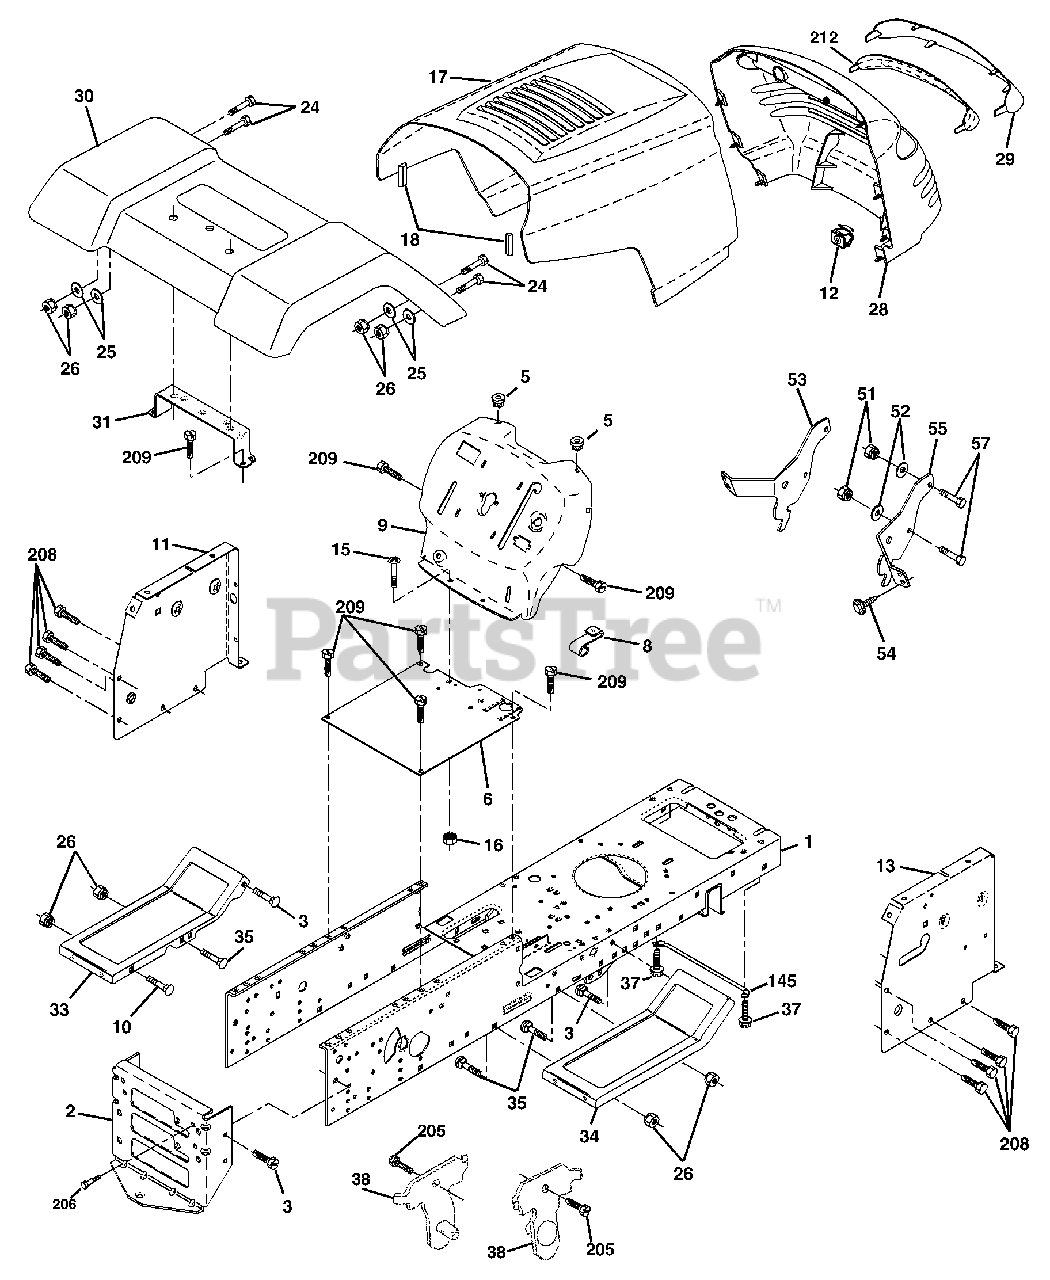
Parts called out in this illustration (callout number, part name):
1	Chassis
2	Drawbar
3	Screw 3/8-16 x 3/4
5	Bumper Hood/Dash
6	Saddle Slkscr Flat Lt 6 Sp
8	Clip Retainer Slide-On
9	Dash
10	Bolt Rd Hd Sqnk. 3/8-16 Unc x 1
11	Panel Asm. Dash Lh
12	Clip Tinnerman Grile P/L
13	Panel Dash Rh
15	Screw Mach Trhd 5/16-18 Unc x 3/4
16	Nut Keps 5/16-18 Unc
17	Hood
18	Bumper Hood
24	Bolt Fin Hex 3/8-16 Unc x 1 Gr. 5
25	Washer 13/32 x 13/16 x 12 Ga.
26	Nut Lock Hex w/Insert 3/8-16 UNC
28	Grill/Lens Asm
29	Lens Grille Private label
30	Fender Asm
31	Bracket Fender
33	Footrest LH
35	Bolt Rd Hd Sht. Sqnk. 3/8-16 x 3/4
37	Screw Thdrol 5/16-18 x 1/2 Tyt
38	Bracket Asm. Pivot Mower Rear
51	Nut Lock Hex W/Ins. 1/4-20
52	Washer 9/32 x 7/8 x 16 Ga.
53	Bracket Grille LH
54	Screw Hex Wshd 8-18 x 7/8
55	Bracket, Grille RH
57	Bolt Fin Hex 1/4-20 x .75
145	Rod Pivot Chassis/Hood
205	Screw Thdrol 3/8-16 x 1/2
206	Bolt shoulder 5/16-18
208	Screw Thdrol 3/8-16 x 1/2
209	Screw Hex Wsh Thdrol 3/8-16
212	Insert Lens Reflector
